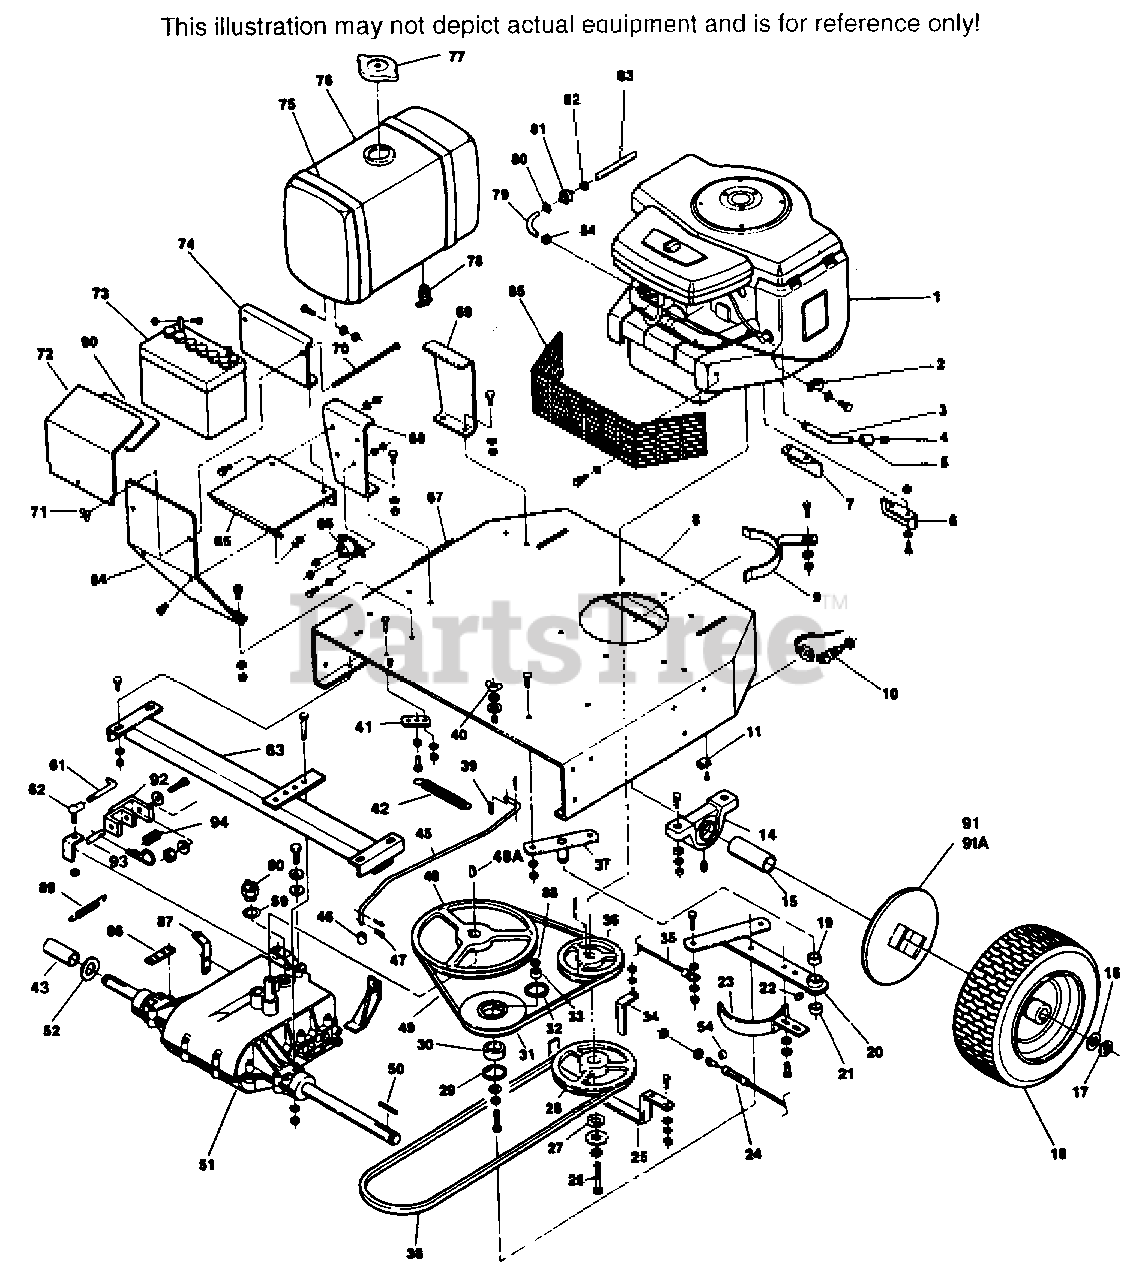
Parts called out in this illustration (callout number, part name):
2	CLAMP
10	SAFETY SWITCH - BLADE CLUTCH
11	CLAMP
14	BEARING, PILLOW BLOCK
16	THRUST WASHER
17	RETAINING RING
18	DRIVE WHEEL ASSY. WITH BRAKE ADAPTER
18A	TIRE ONLY
18B	RIM ONLY
19	BRONZE BEARING
20	IDLER ARM WELDMENT
21	BRONZE BEARING
22	GREASE FITTING
23	BELT GUIDE - IDLER PULLEY
24	FOOT CLUTCH CABLE ASSY.
26	BOLT, HEX HD., 7/16-20 X 1-1/2
27	SPACER CRANKSHAFT
28	PULLEY, ENGINE
29	RETAINING RING
30	BEARING, IDLER PULLEY
31	PULLEY, IDLER
32	RETAINING RING
33	SLEEVE
36	PULLEY, ENGINE
37	IDLER PIVOT WELDMENT
39	HAIRPIN
40	WING NUT
41	SPRING MOUNTING BRACKET
42	SPRING, BELT CLUTCH
45	BELT CLUTCH ROD
46	SLEEVE
47	HAIRPIN
48	PULLEY, TRANSAXLE
48A	WOODRUFF KEY #9
50	KEY, 3/16 X 3/16 X 3-1/2
51	TRANSAXLE
52	THRUST WASHER
54	FOOT CABLE SLEEVE
58	SHIFT LEVER
59	FIBER WASHER - .010
59	FIBER WASHER - .020
60	NEUTRAL SAFETY SWITCH
61	SHIFT CONNECTOR ROD
62	BALL JOINT
64	BATTERY SUPPORT
65	BATTERY SHELF
66	STARTER SOLENOID
67	HITCH BRACKET WELDMENT - RH
68	FUEL TANK BRACKET, FRONT
69	FUEL TANK BRACKET, REAR
70	BOLT, CARRIAGE 1/4-20 X 6
71	WING NUT
72	BATTERY COVER
73	BATTERY
74	BATTERY CLAMP
75	FUEL TANK STRAP
76	FUEL TANK, 3 GALLON
77	FUEL TANK CAP
78	FUEL SHUT-OFF VALVE
80	HOSE CLAMP
81	FUEL FILTER
82	HOSE CLAMP
84	HOSE CLAMP
86	SPACER, TRANSAXLE MOUNTING
87	REAR BRACE, TRANSAXLE
88	SPACER, IDLER PULLEY
89	SPRING, BRAKE RETURN
90	BATTERY COVER INSULATION
92	SAFETY REVERSE WELDMENT
93	SAFETY REVERSE ROD
94	SPRING, SAFETY REVERSE
